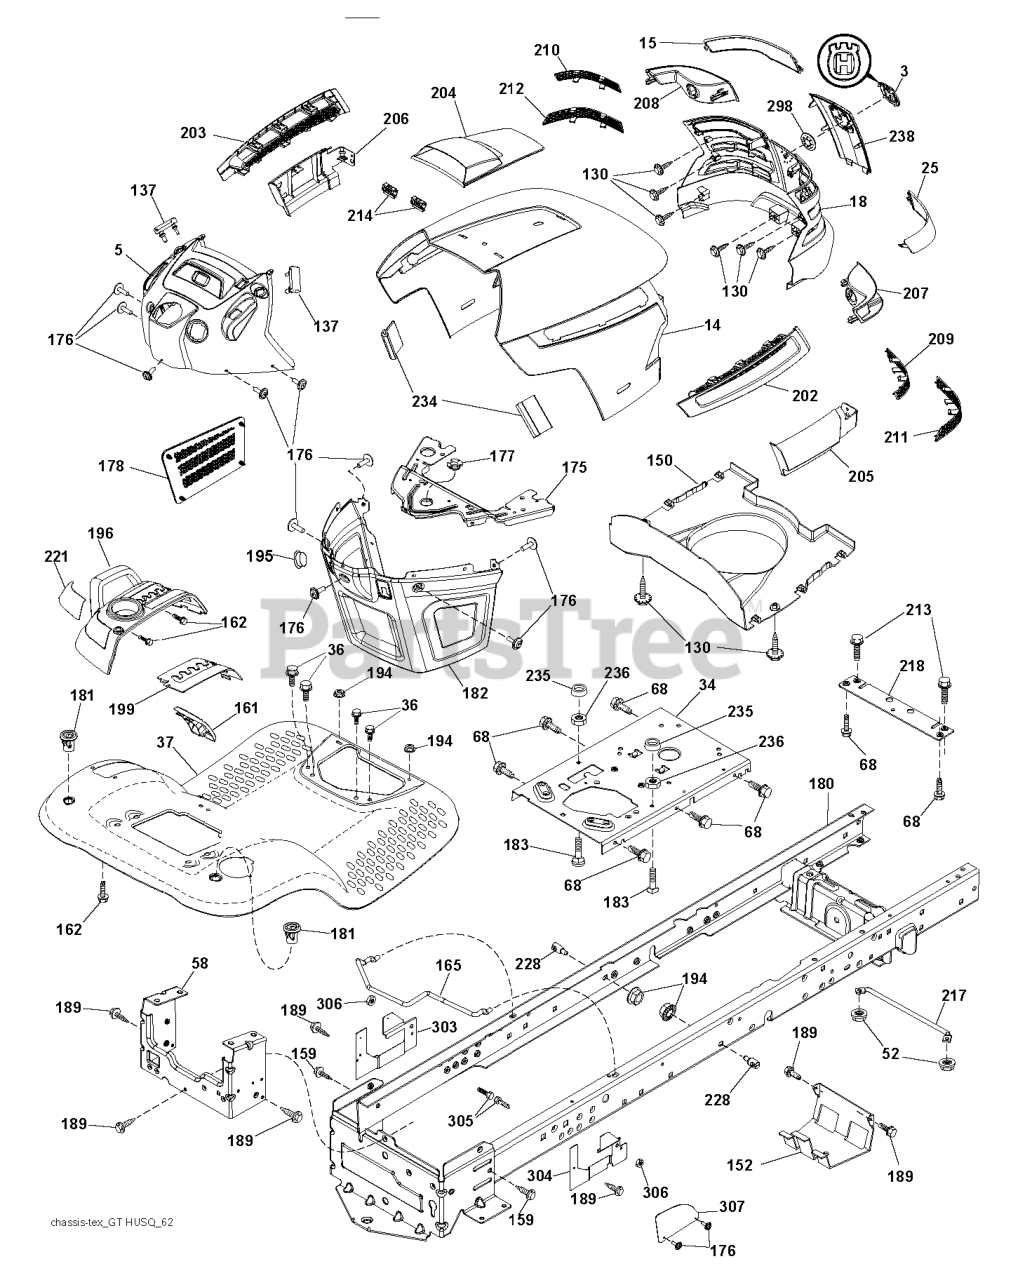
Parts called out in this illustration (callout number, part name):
3	RP LOGO
5	DASH.ASM.HUSQ.GT.E.RECT.W/CK
14	HOOD
15	LENS.LH.TEX.GT.HUSQ.CL
18	GRILL.ASM.HUSQ.TG/CRD.W/TRIM
25	LENS.RH.TEX.GT.HUSQ.CL
34	PLATE.ENGINE.WELDED.CHASSIS
36	SCREW 5/16"
37	FENDER.PNT.TX.GT.CH/FW.ORANGE
52	LOCKNUT
58	DRAWBAR.UPPER.2PC,LRG.FENDER
68	Screw 5/16-18 x 1/2 Hex, Self Tapping 5/16-18 x 1/2
130	SCREW.#10 X 0.750.BOS
137	BUMPER DASH
150	AIR.DUCT.HOOD.TEX.GT.HUSQ
152	SHIELD.BROWNING.W/TEX
159	SCREW, 3/8-16X3/4
161	CONSOLE.FUEL.WINDOW.HU
162	SCREW.HI-LO.CONSOLE
165	SUPPORT.TANK.REAR.W/TEX
175	PLATE.CROSSMEMBER.HUSQ
176	SCREW.#10-24X5/8.RN.QU
177	BUSHING, STEERING
178	CARGO.ASM.NET.TXGT.W/C
180	CHASS.WLDMNT.TLT.12GA/2PC.20"
181	BUSHING.MNT.FEND.CRGO.
182	DASH.LOWER.COMMON.12V.ADAPTOR
183	BOLT.5/16-18X1-1/4 FULL.THREAD
189	SCREW
194	NUT LOCK HEX FLANGE 5/16-18
195	PLUG.HOLE.DASH.LOWER.12V.BLK
196	RP CONSOLE.ASM.DECKLFT.W/
199	PLATE.DECK.LIFT.HUSQVARNA.GT
202	VENT.SIDE.HOOD.HUSQ.RH.GREY
203	VENT.SIDE.HOOD.HUSQ.LH.GRAY
204	HOOD VENT
205	SKIRT.HOOD.SIDE.HUSQ.RH.GREY
206	SKIRT.HOOD.SIDE.HUSQ.LH.GREY
207	BEZEL.RH.TEX.GT.HUSQ
208	BEZEL.LH.TEX.GT.HUSQ
209	INSERT.HEX.GRILL.HUSQ.GREY
210	INSERT.HEX.GRILL.HUSQ.
211	INSERT.HEX.GRILL.HUSQ.
212	INSERT.HEX.GRILL.HUSQ.
213	BOLT
214	CLIP.RETAINER.TINNER.
217	ROD.PIVOT.HOOD
218	X-PIECE.HOOD.STOP.NON/
221	REFLECTOR.LH.TEX GT HU
228	STUD.FASTNER.W/ANTI-ROTATE
234	BUMPER.HOOD.TEX.HUSQVARNA
235	SPACER FENDER
236	NUT.CENTERLOCK.5/16-
238	TRIM.HUSQ.TG/CRD.SERVICE
298	NUT PUSH M
303	SHIELD CHASSIS LEFT
304	SHIELD CHASSIS RIGHT
306	NUT LOCK FLG 3/8-16 UNC
307	SHIELD UPPER PEDAL
